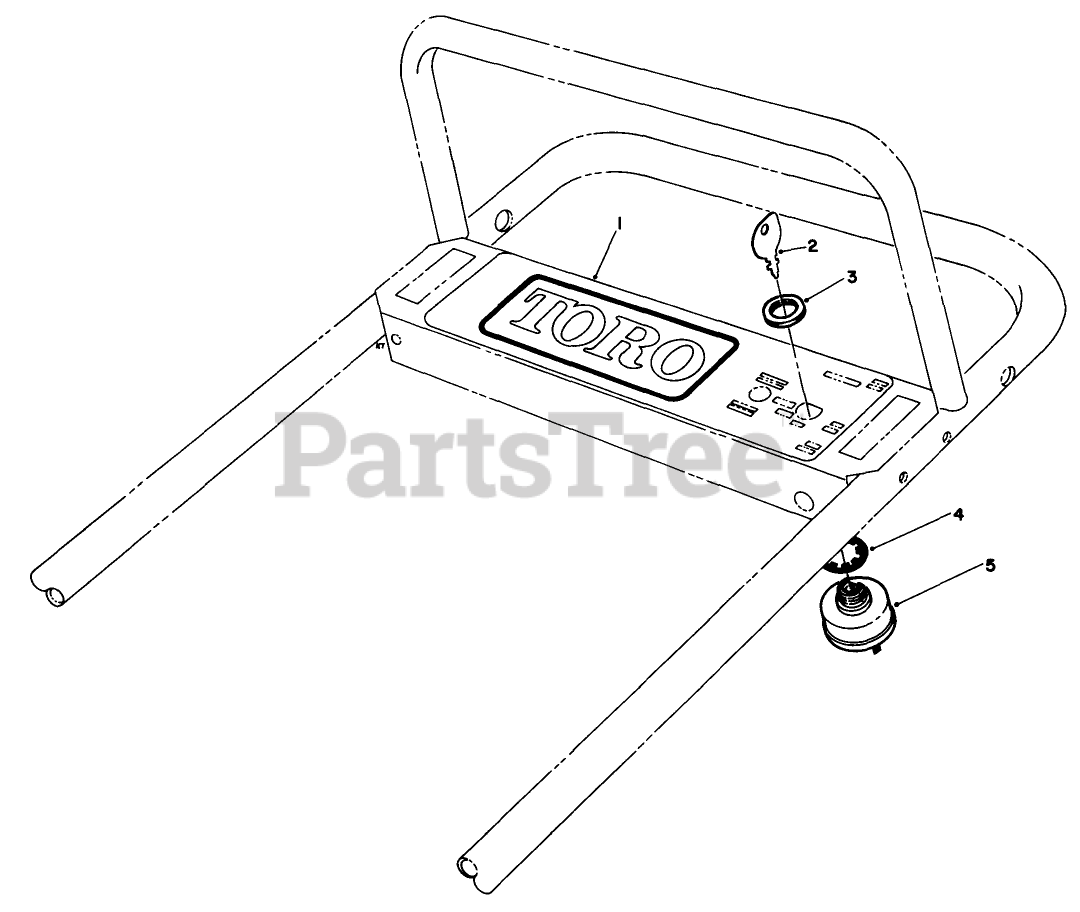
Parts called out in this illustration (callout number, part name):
3	NUT-HH
4	WASHER-LOCK
5	SWITCH-STARTER
